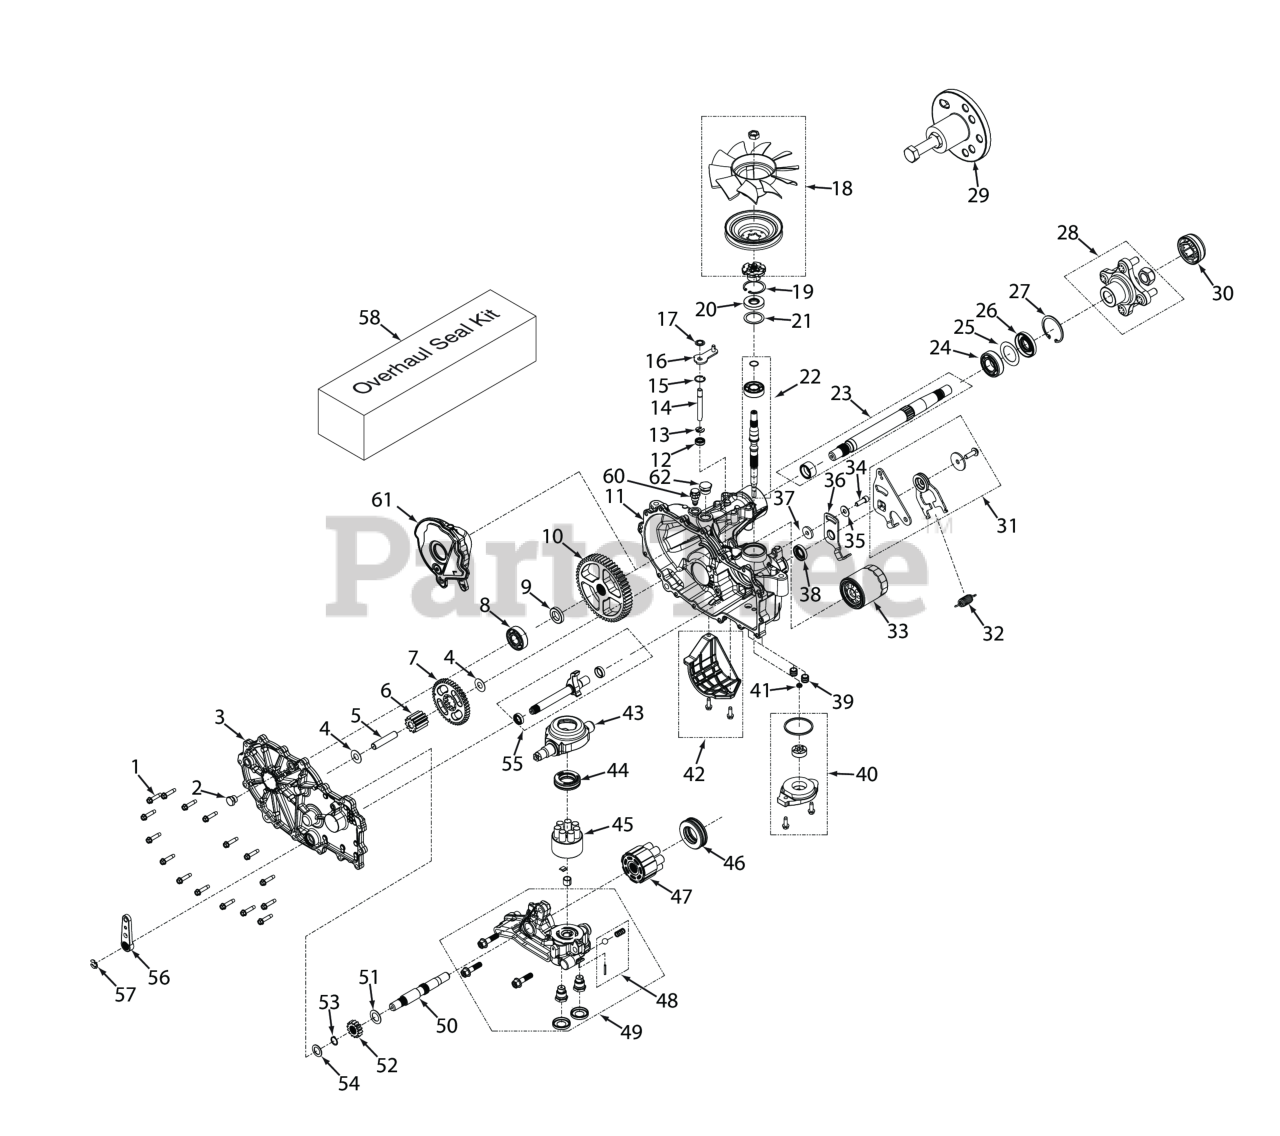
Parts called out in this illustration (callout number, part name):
1	Bolt, Hex Head 1/4-20 x 1-1/8"
2	Plug, External Hex Vent 9/16-18
3	Kit, Side Cover LH
4	Washer, .5 x 1.0 x .03
5	Jackshaft Pin
6	Gear, 11T Steel
7	Gear, 45T
8	Kit, Bearing
9	Spacer, .750 x 1.320 x .257
10	Gear, 54T
11	Kit, Main Housing LH, Charge, Control
12	Seal, Lip, .375 x .75 x .25
13	Ring, .Retaining .375 External
14	Rod, By-Pass
15	R i n g , Retaining .750 Internal
16	Arm, Bypass (LH)
17	Ring, Retainging .375 External
18	Kit, Fan/Pulley
19	R i n g , Retaining 2.06 Internal
20	Seal, Lip 17 x 40 x 7
21	Washer, 1.23 x 1.56 x .04
22	Kit, Input Shaft
23	Kit, Shaft, Axle
24	Bearing, Ball 1.0 x 52 x 15 Open
25	Spacer, 1.355 x 2.035 x .021
26	Seal, Lip TC4 1.0 x 2.06 x .38
27	R i n g , Retaining 2.06 Internal
28	Hub, 4-Bolt
29	Kit, Hub Puller
30	Cap, Axle
31	Kit, RTN Bi-Directional (Right Side)
32	Spring, Extension, RTN - 44lbs
33	Filter, Oil
34	Bolt, Hex Head Cap Screw 5/16-24 x 1" Patch
35	Washer, 7/16 x 7/8 OD x .06 HT
36	Arm, Neutral (Left Side)
37	Spacer, .32 ID x 1.005 OD x .1495 Thk
38	Seal, Lip 18 x 32 x 7
39	Tube, Charge Triple O-ring
40	Kit, Charge Pump
41	Kit, Gerotor Seal
42	Kit, Filter Guard (LH)
43	Trunnion, Swashplate
44	Ball Thrust Bearing
45	Kit, Cylinder Block
46	Thrust Ball Bearing Assembly
47	Kit, 16cc Cylinder Block Assembly (steam
48	Kit, Charge Relief
49	Kit, Center Section, LH Charge
50	Shaft, Motor
51	Washer, .72 x 1.16 x .04
52	Gear, 14T Steel
53	Ring, Retaining .625
54	Washer, HT .62 ID x 1.0 OD x .05 Thick
55	Kit, Inboard, RH Rot B / LH Rot A (LH)
56	Handle, Brake
57	Ring, Retaining External .375"
58	Kit, Seal (ZT-2800)
59	Tube, Sealant
60	Fitting 9 /16 - 18, Breather
61	Expansion Tank, Internal LH
62	Plug, 3/4-16
